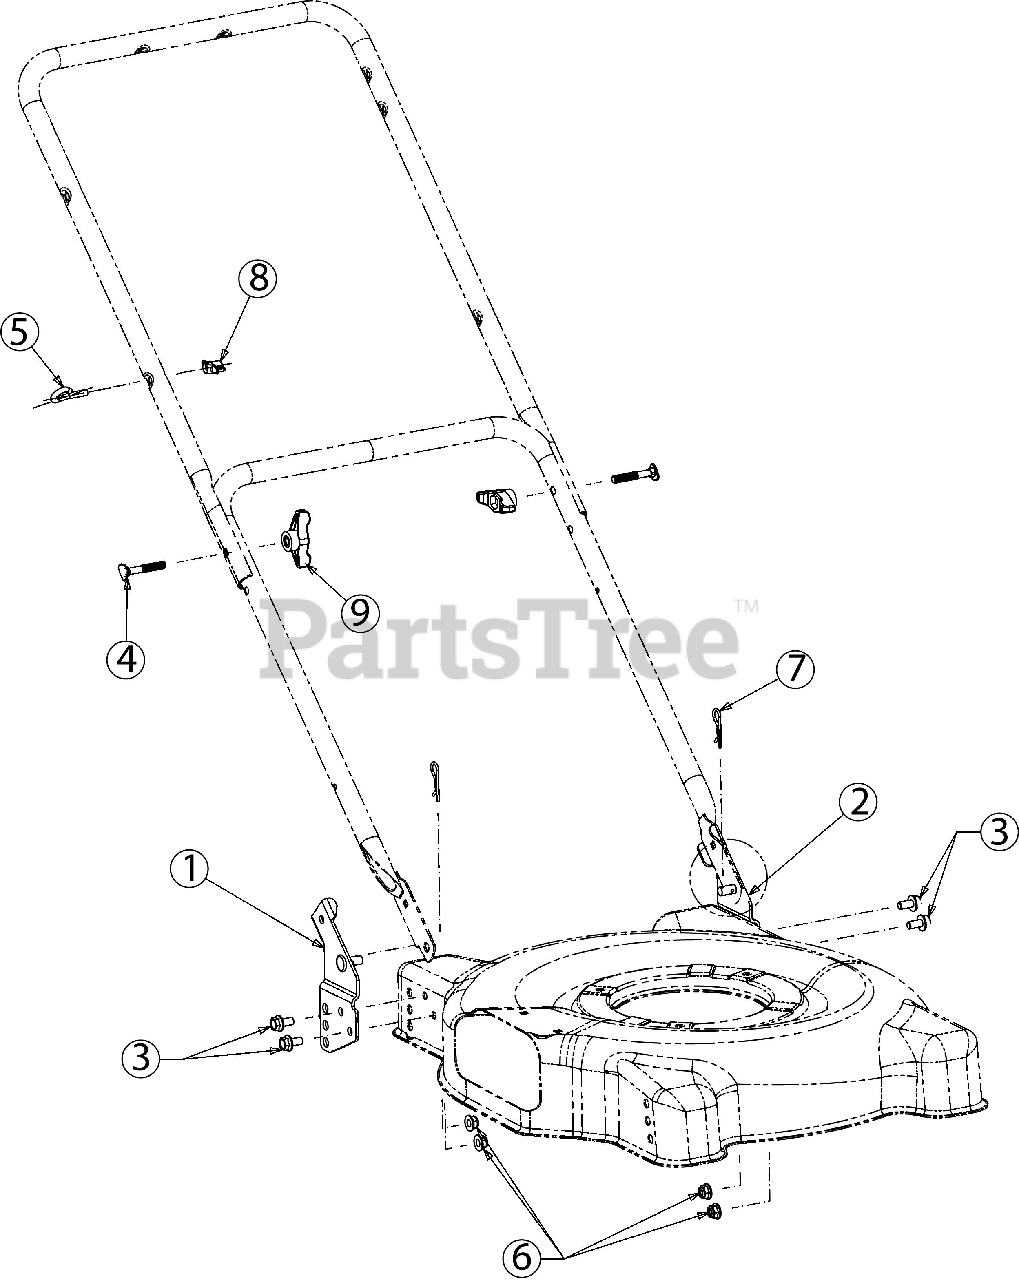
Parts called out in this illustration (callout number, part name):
1	HANDLE BRACKET ASSEMBLY (RH)
2	HANDLE BRACKET ASSEMBLY (LH)
3	SCREW 5/16-18 X .625 GR5
4	SCREW 5/16-18 X 2.0
5	EYEBOLT 1/4-20
6	FLANGE LOCK NUT 5/16-18
7	INTERNAL COTTER PIN
8	HANDLE KNOB
9	WING KNOB 5/16-18
